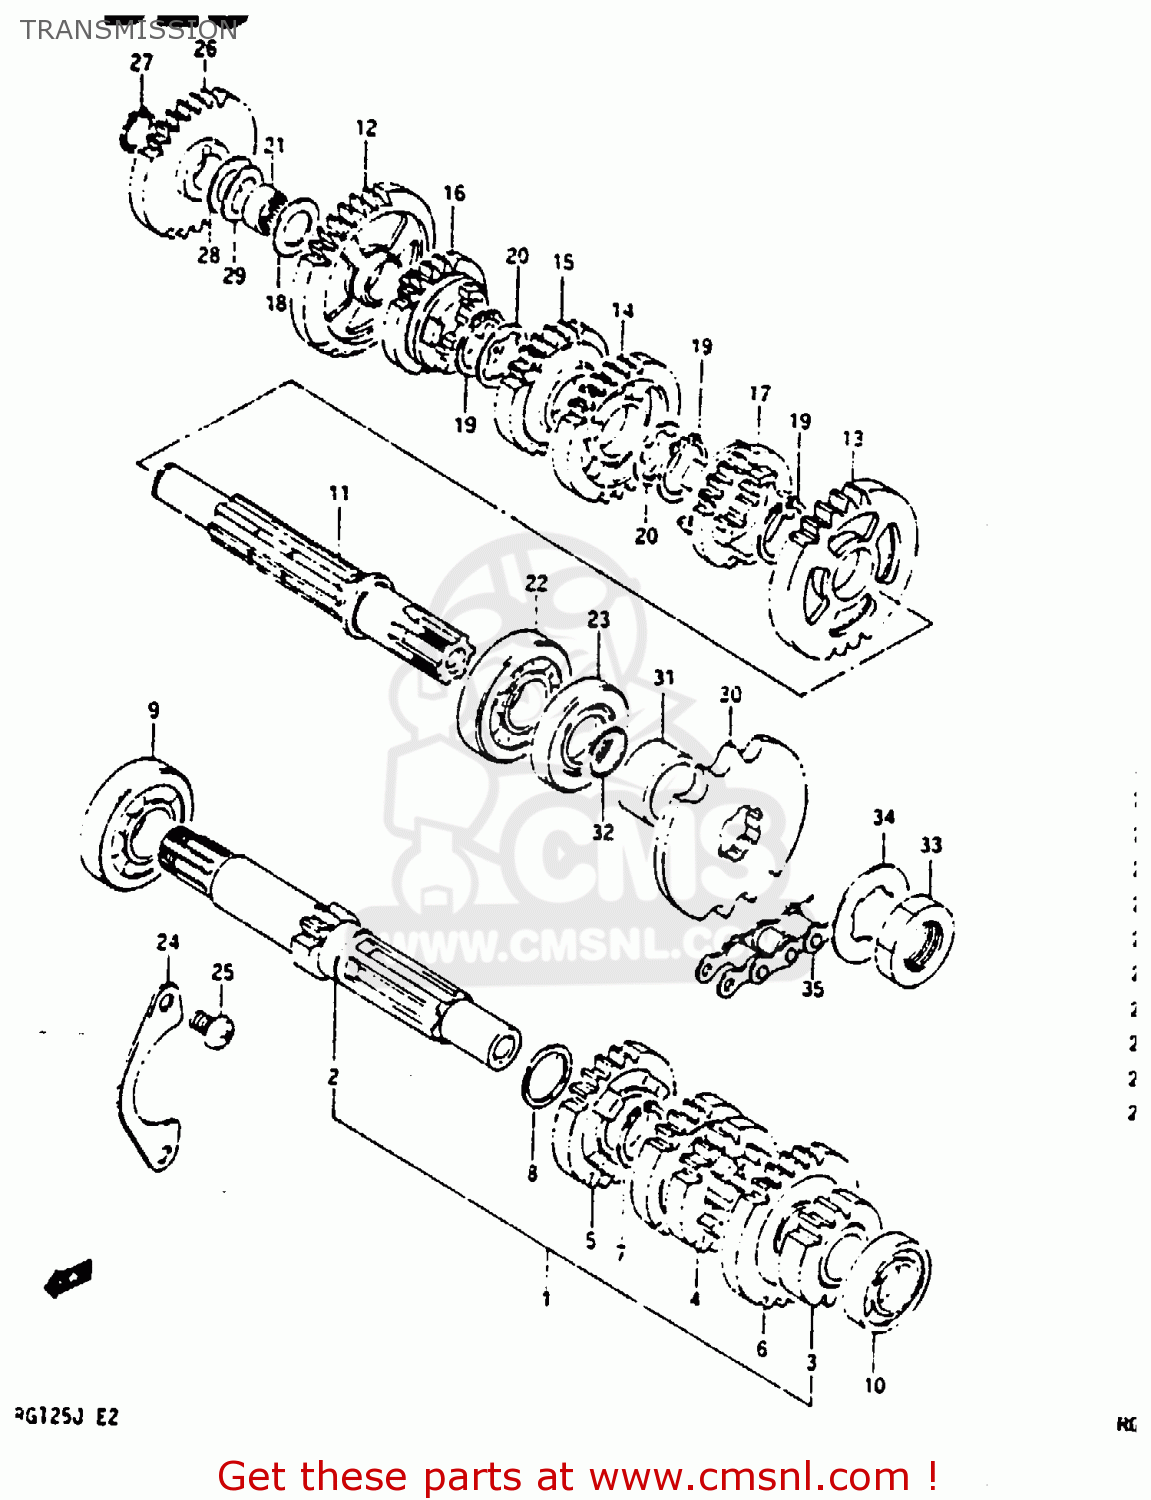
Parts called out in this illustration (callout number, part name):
1	COUNTERSHAFT ASSY
2	COUNTERSHAFT (NT:12)
3	GEAR,2ND DRIVE(NT:14)
4	GEAR,3RD & 4TH DRIVE
5	GEAR,5TH DRIVE
6	GEAR, 6TH DRIVE (NT:25)
7	CIRCLIP
8	WASHER
9	BEARING
10	BEARING
11	DRIVESHAFT
12	GEAR,1ST DRIVEN
13	GEAR, 2ND DRIVEN (NT:26)
14	GEAR,3RD DRIVE
15	GEAR,4TH DRIVEN
16	GEAR, 5TH DRIVEN (NT:22)
17	GEAR, 6TH DRIVEN (NT:21)
18	WASHER,THRUST
19	CIRCLIP
20	WASHER,LOCK
21	BEARING(15X33X12)
22	BEARING
23	SEAL,OIL(27X38X5)
24	RETAINER, BEARING
25	SCREW 6X12
26	GEAR,KICK STARTER IDLE
27	CIRCLIP,15MM
28	SHIM
29	WASHER
30	SPROCKET,ENGINE(NT:15)
31	SPACER(20X27X13.1)
32	O RING(D:1,ID:19.5)
33	NUT
34	WASHER,LOCK
35	CHAIN, DRIVE (428*128L)
